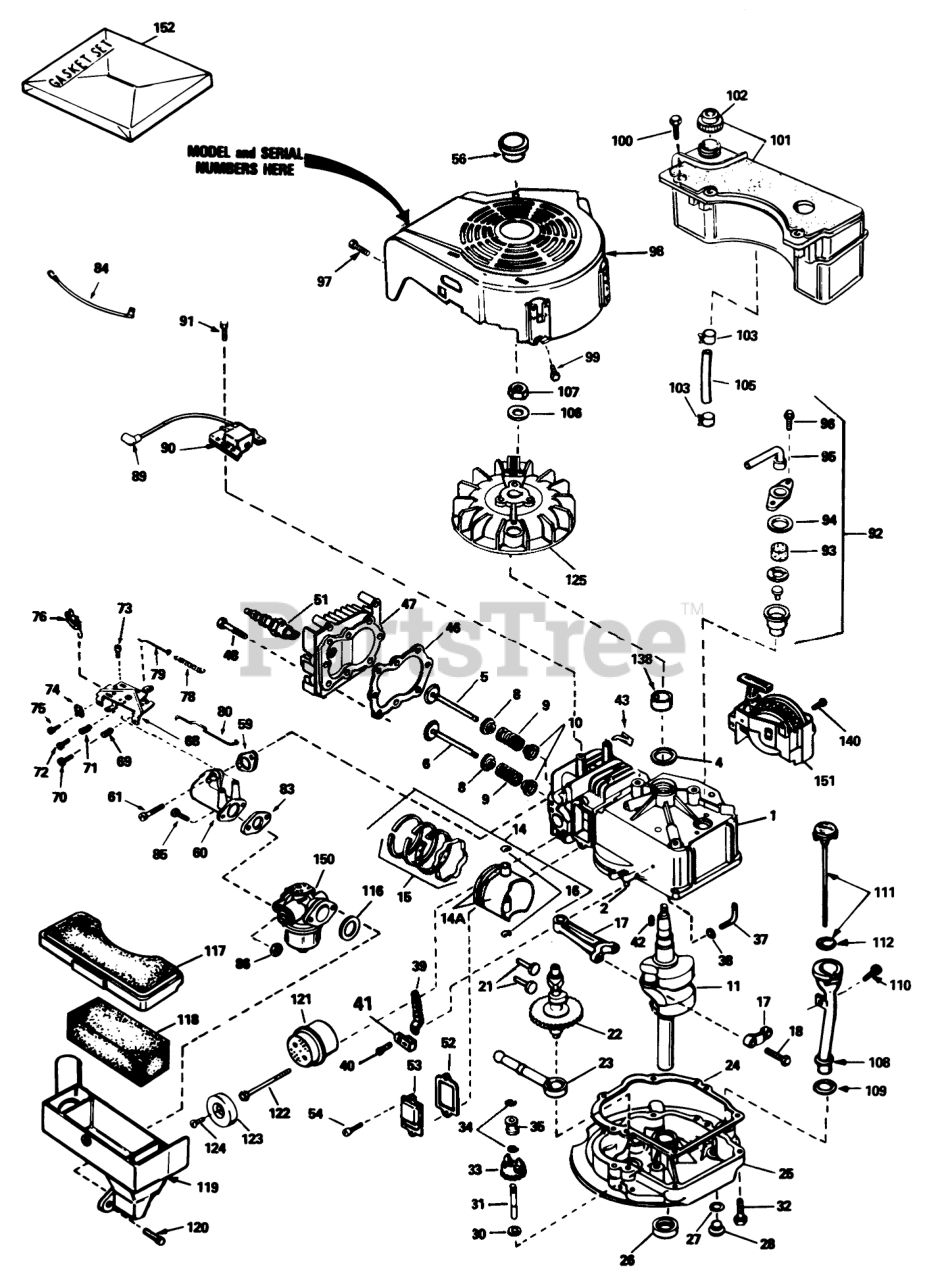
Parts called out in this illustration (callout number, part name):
1	Cylinder Assembly (Incl. Ref. #2, 4, 94 & 96)
2	Pin-Dowel
4	Seal-Oil
5	Valve-Intake (Std)(Incl. Ref. #10)
5	Valve-Intake (1 /32" oversize)(Incl Ref. #10)
6	Valve-Exhaust (Std)(Incl. Ref. #10)
6	Valve-Exhaust (1/32" oversize) (Incl. Ref. #10)
8	Cap-Upper Valve Spring
9	Spring-Valve
10	Cap-Valve, Spring
11	Crankshaft
14	Piston-Pin & Ring Assy. (Std.)(Incl. Ref. #14A, 15 & 16)
14	Piston-Pin & Ring Assy. (.010 oversize)(Incl. Ref. #14A, 15 & 16)
14	Piston-Pin & Ring Assy. (.020 oversize)(Incl. Ref. #14A, 15 & 16)
14A	Piston & Pin Assy. (Std)(Incl. Ref. #16)
14A	Piston & Pin Assy. (.010 oversize) (Incl. Ref. #16)
14A	Piston & Pin Assy. (.020 oversize) (Incl. Ref. #16)
15	Piston Ring Set Std.
15	Piston Ring Set .010 O.S.
15	Piston Ring Set .020 O.S.
16	Ring-Retaining, Piston Pin
17	Rod Assy.-Connecting (Incl. Ref. #18)
18	Bolt-Rod, Connecting
21	Lifter-Valve
22	Camshaft(Mech.Comp. Release)
23	Oil Pump ASM
24	Gasket
25	Flange Assy.-Mounting (Incl. Ref. #26, 27, 28 & 31)
26	Seal Oil
27	Gasket-Oil Drain
28	Plug Oil Drain
30	Washer-Flat
31	Shaft-Governor
32	Screw (1/4-20 x 1-1/4)
33	Gear Assembly-Governor (Incl. Ref. #30)
34	Ring-Retaining
35	Spool-Governor
37	Governor Rod ASM
38	Washer-Flat
39	Governor Lever
40	Screw
41	Clamp-Lever, Governor
42	Key-Flywheel
46	Gasket-Cylinder Head
47	2025A67 ADD.ASSEMBL
48	Screw
51	Plug, Spark (J17LM or equiv.)
51	Plug, Spark (Champion RCJ-8)
52	Gasket-Breather
53	Cover-Valve
56	Plug, Screen
59	Gasket-Intake
60	Pipe-Intake (Incl. Ref. #59)
61	Screw (1/4-20 x 1)
68	Control Assy.-Remote Speed (Incl. Ref. #69 thru 72 & 76)
69	61709/GIL1515A/95-5
70	Screw
71	Spring-Compression
72	Screw
73	Screw (10-24 x 9/16)
74	Conduit
75	Screw (10-32 x 3/8)
76	Terminal
78	Spring Governor
79	2035A67 ADD.ASSEMBL
80	Link-Throttle
83	Gasket
84	Wire-Ground
85	Screw (1/4-28 x 7/8)
86	Nut and Lock Washer (1/4-28)
89	Cover-Spark Plug
90	Solid State
91	Screw
92	Breather Assembly (Incl. Ref. #93 thru 96)
93	Element-Breather
94	Gasket-Breather
95	Tube, Breaker
96	Screw (10-24 x 9/16)
97	Screw (10-24 x 9/16)
98	Housing-Blower
99	Screw (1/4-20 x 1/2)
100	Screw (10-32 x 35/64)
101	Tank Assembly-Fuel (Incl. Ref. #102)
102	Cap-Fuel
103	Clamp-Line, Fuel
105	Line-Fuel
106	Washer-Belleville
107	Nut-Flywheel
108	Tube-Oil Fill
110	Screw (10-32 x 1/2)
111	Dipstick-Oil (Incl. Ref. #112)
116	Gasket-Cleaner, Air
117	Cover Air Cleaner
118	Filter-Air Cleaner
119	Body Air cleaner
121	Muffler (Incl. Ref. #122)
123	Cover-Muffler
124	Screw
125	Flywheel
140	Screw (1/2-20x5/8)
150	Carburetor (Incl. Ref. #83)
151	Starter-Sidemount
152	Gasket Set
